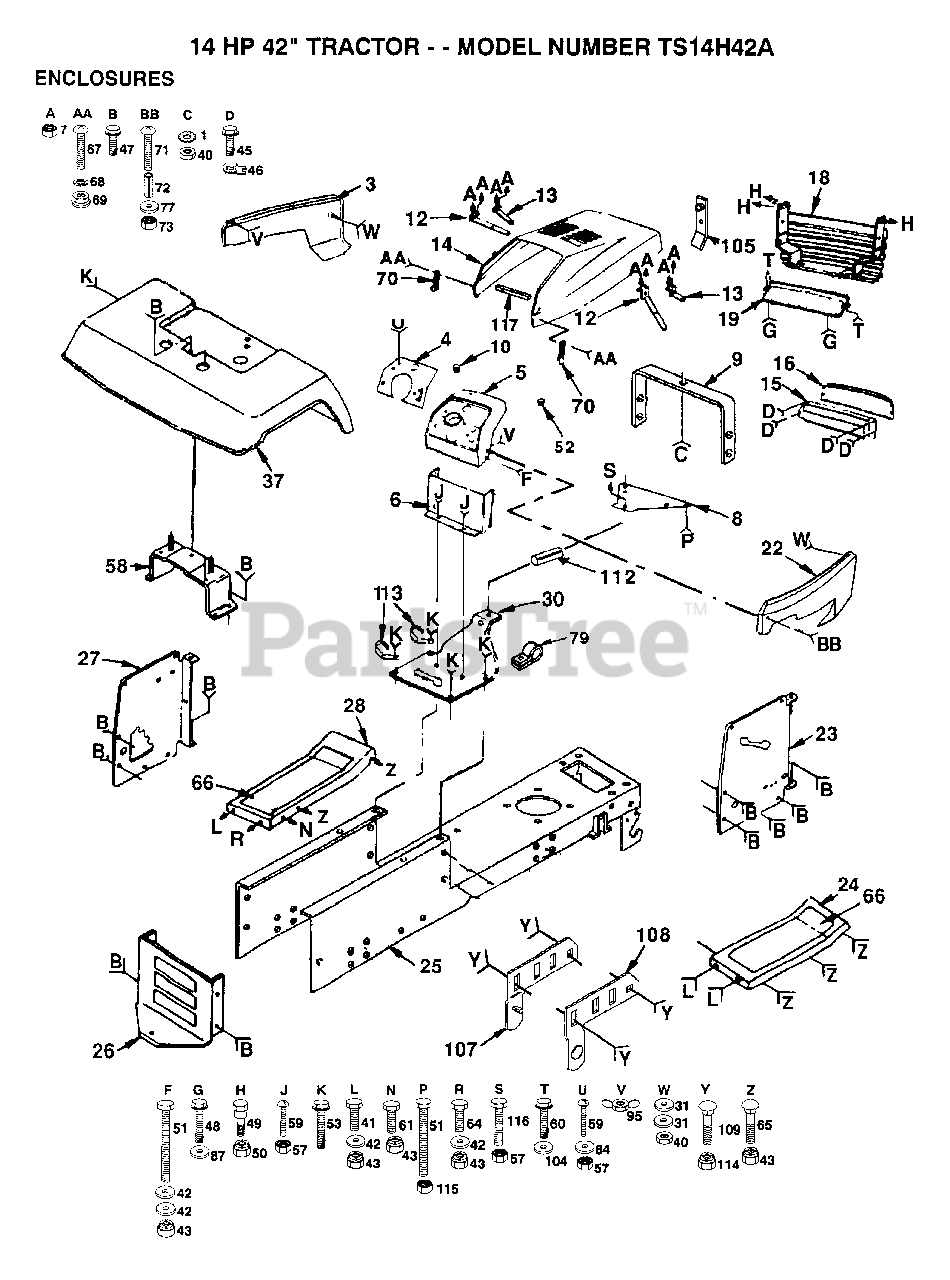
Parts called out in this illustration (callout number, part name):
6	DASH ASSY LT
7	NUT
9	SUPPORT ASS'Y
10	PLUG BUTTON T
16	LENS LT
23	PANEL.DASH.RH
25	CHASSIS ASM
27	PANEL.DASH.LH
30	SADDLE.LT.GOOSE
31	WASHER PM
42	WASHER
46	"""J"" FASTENER LT"
47	SCREW
48	SCREW
52	PLUG DOME
53	SCREW LT
58	BRKT FENDER
59	SCREW
60	SCREW HEX CRT
65	BOLT
66	FOOTREST PAD
67	SCREW
68	LOCKWASHER
69	WELDNUT
70	HOOD LATCH T
71	SCREW
72	SPACER LT
77	WASHER
79	CLIP T
84	WASHER
87	WASHER
104	WASHER
107	PIVOT BRKT LH
108	PIVOT BRKT RH
112	SPACER
113	"CLIP,INSULATOR"
114	NUT
115	NUT
116	BOLT
